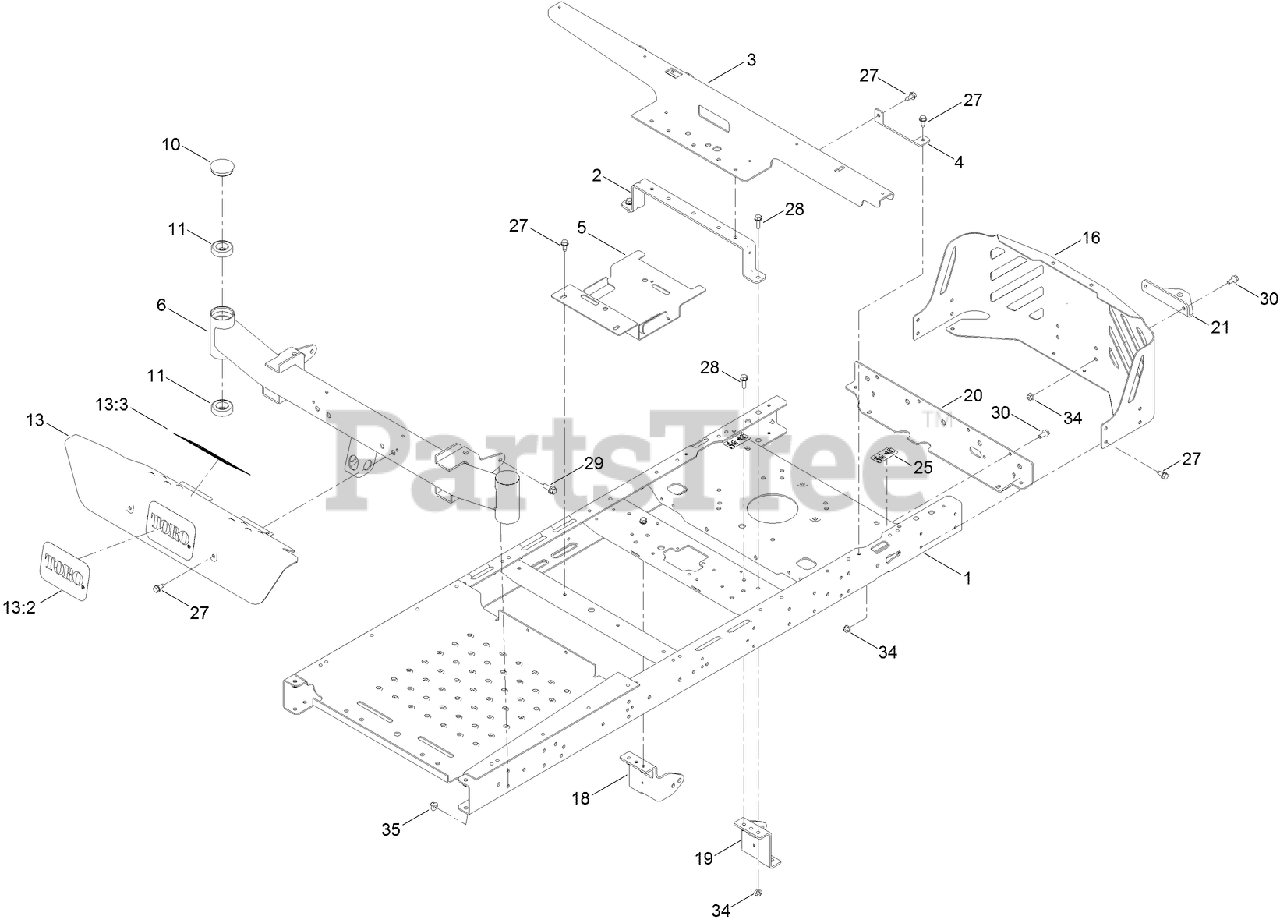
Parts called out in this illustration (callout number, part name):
1	RIVETED FRAME ASM (WIDE LEVER)
2	BRACE-SEAT, REAR (WIDE)
3	SUPPORT-POD, WIDE
4	SUPPORT-TANK, REAR
5	BRACKET-BATTERY
6	AXLE ASM
10	CAP-GREASE
11	BEARING-BALL
13	FOOTREST ASM
13:2	DECAL
13:3	DECAL-DANGER
16	GUARD-ENGINE, WIDE
18	MOUNT-HYDRO, FRONT (RH)
19	MOUNT-HYDRO, FRONT (LH)
20	CROSSMEMBER-REAR, WIDE
21	BRACKET-HITCH
25	DECAL-BYPASS
27	SCREW-HWHTF
28	SCREW-HHF
29	SCREW-HHF
30	SCREW-HHF
34	NUT-HF, NI
35	NUT-HF, NI
